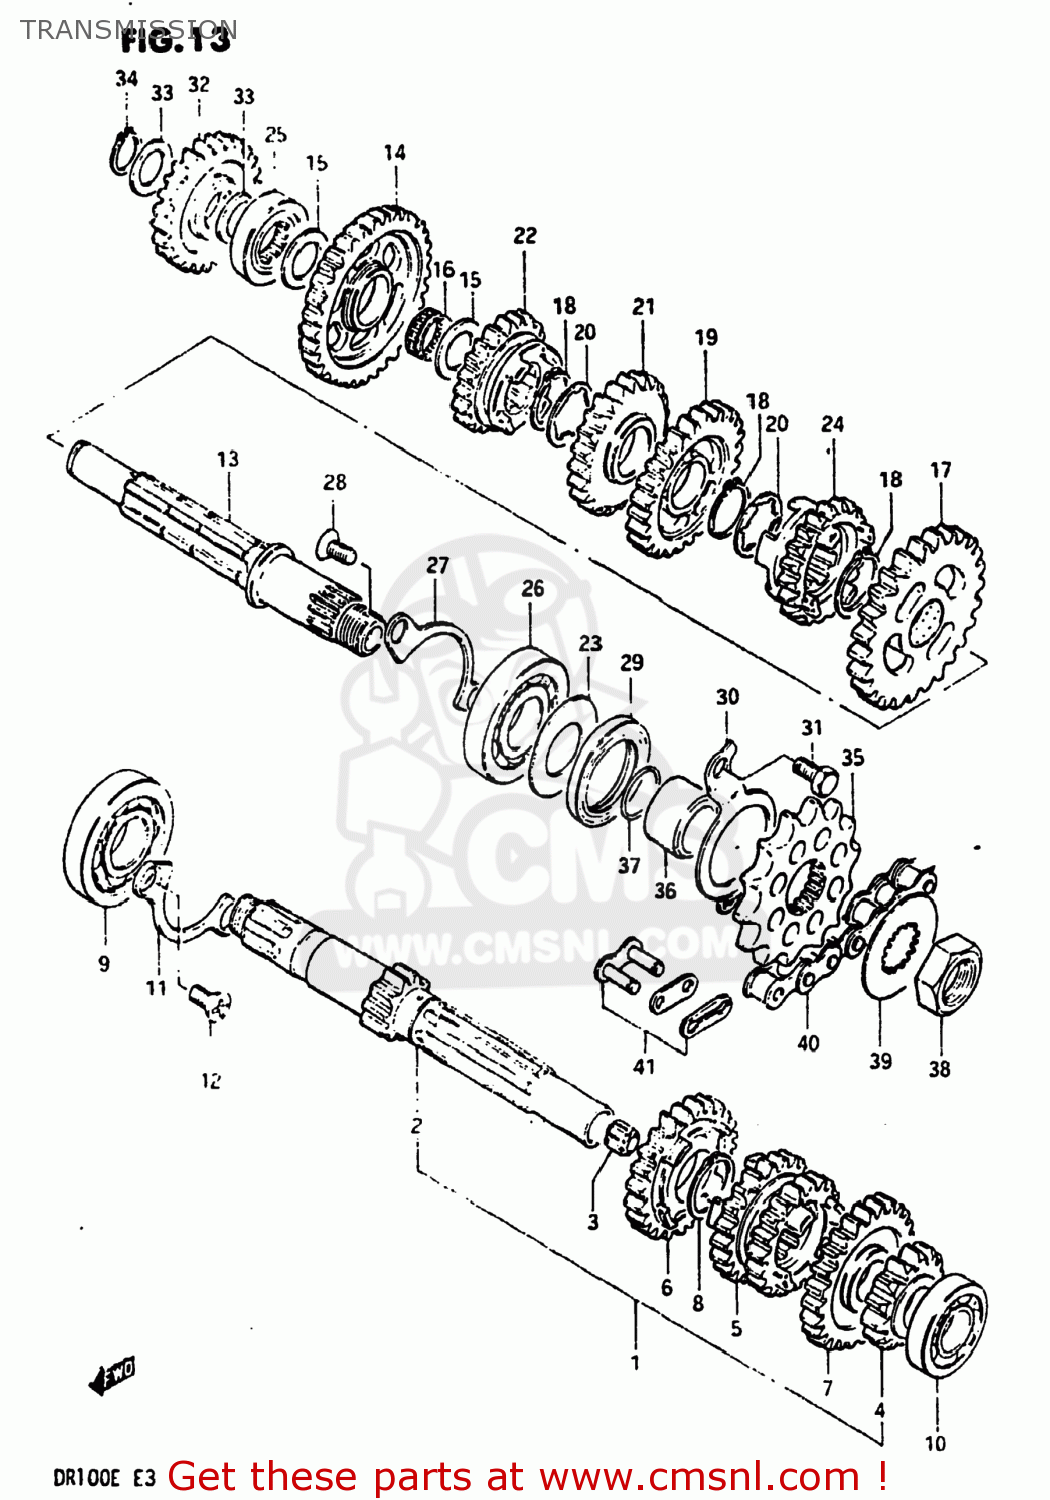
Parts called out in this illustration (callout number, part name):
1	SHAFT,COUNTER
2	SHAFT,COUNTER
3	BUSHING
4	GEAR,SECOND DRIVE
5	GEAR,THIRD & FOURTH DRIVE,N
6	GEAR,FIFTH DRIVE
7	GEAR,SIXTH DRIVE
8	CIRCLIP
9	BEARING
10	BEARING, LH
11	RETAINER,DRIVE SHAFT BEARING
12	SCREW
13	SHAFT,DRIVE
14	GEAR,FIRST DRIVEN
15	WASHER
16	BEARING(15X19X7.8)
17	GEAR,SECOND DRIVEN
18	CIRCLIP
19	GEAR,THIRD DRIVEN
20	WASHER,LOCK
21	GEAR,FOURTH DRIVEN
22	GEAR,FIFTH DRIVEN
23	WASHER,OIL SEALING
24	GEAR,SIXTH DRIVEN
25	BEARING(15X33X12)
26	Bearing
27	RETAINER,DRIVE SHAFT BEARING
28	SCREW
29	SEAL,OIL(27X40X6)
30	PLATE,DRIVESHAFT OIL
31	BOLT
32	GEAR,KICK STARTER IDLE(NT:26)
33	WASHER
34	CIRCLIP,15MM
35	SPROCKET,ENGINE(NT:13)
36	SPACER
37	O RING(D:2.4,ID:19)
38	NUT
39	WASHER,LOCK
40	CHAIN ASSEMBLY,DRIVE
41	JOINT,CHAIN
